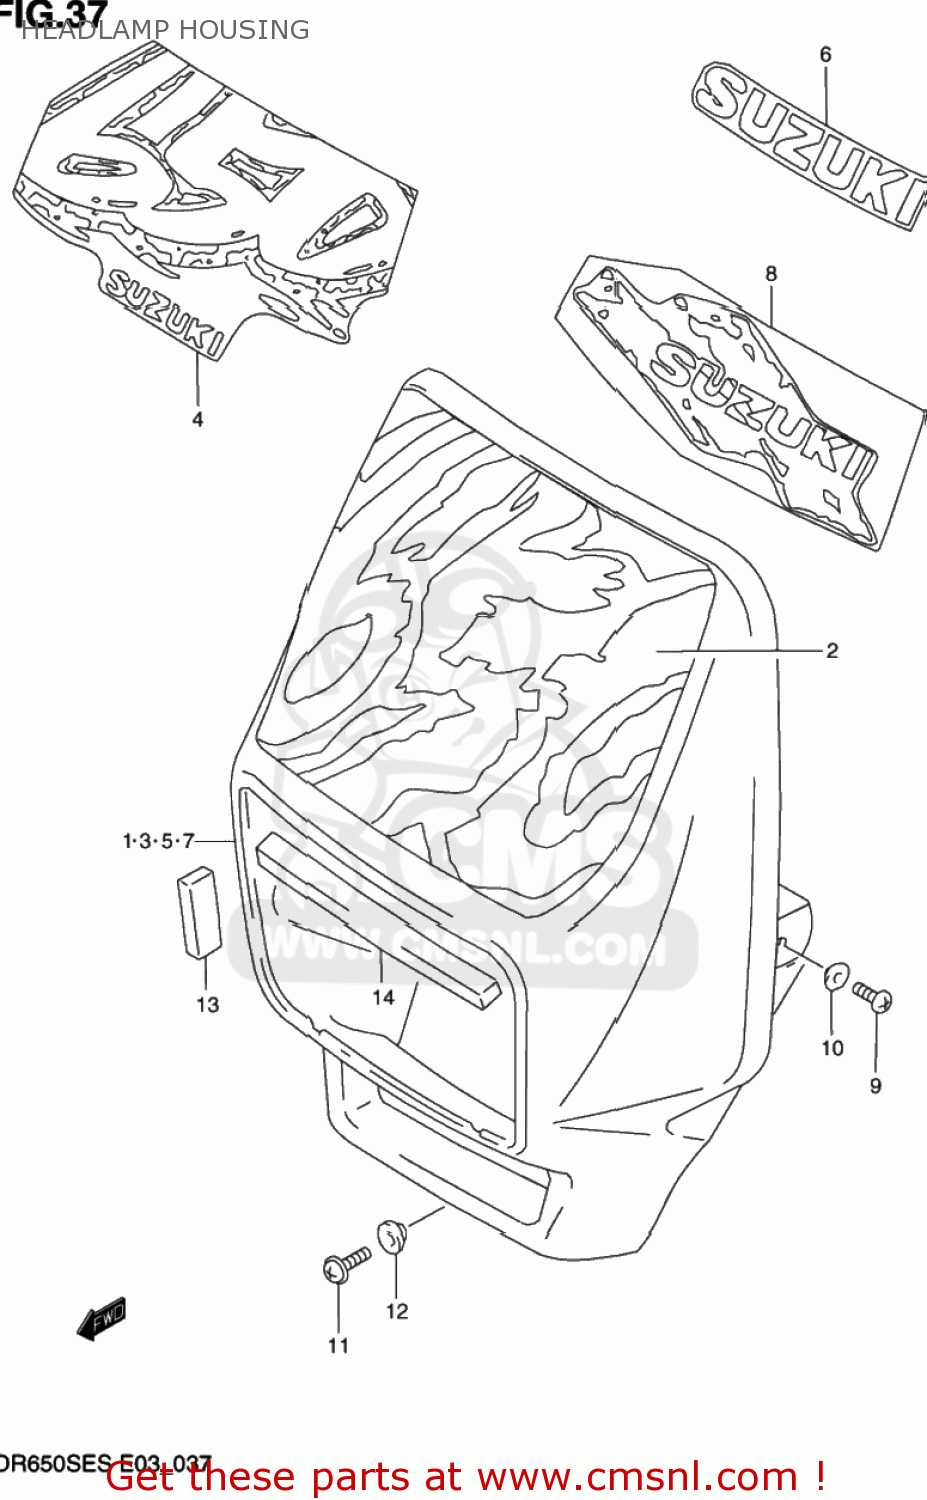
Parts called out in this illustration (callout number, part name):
1	HOUSING ASSEMBLY,HEADLAMP
2	TAPE,HEADLAMP COVER
3	HOUSING ASSEMBLY,HEADLAMP
4	TAPE,HEADLAMP COVER
5	HOUSING ASSEMBLY,HEADLAMP
6	EMBLEM,HEADLAMP COVER
7	COVER,HEADLAMP
8	TAPE,HEADLAMP COVER
9	SCREW 6X12
10	WASHER
11	SCREW
12	WASHER(5.2X14X1.5)
13	CUSHION,HEADLAMP COVER
14	CUSHION,HEADLAMP COVER SIDE
